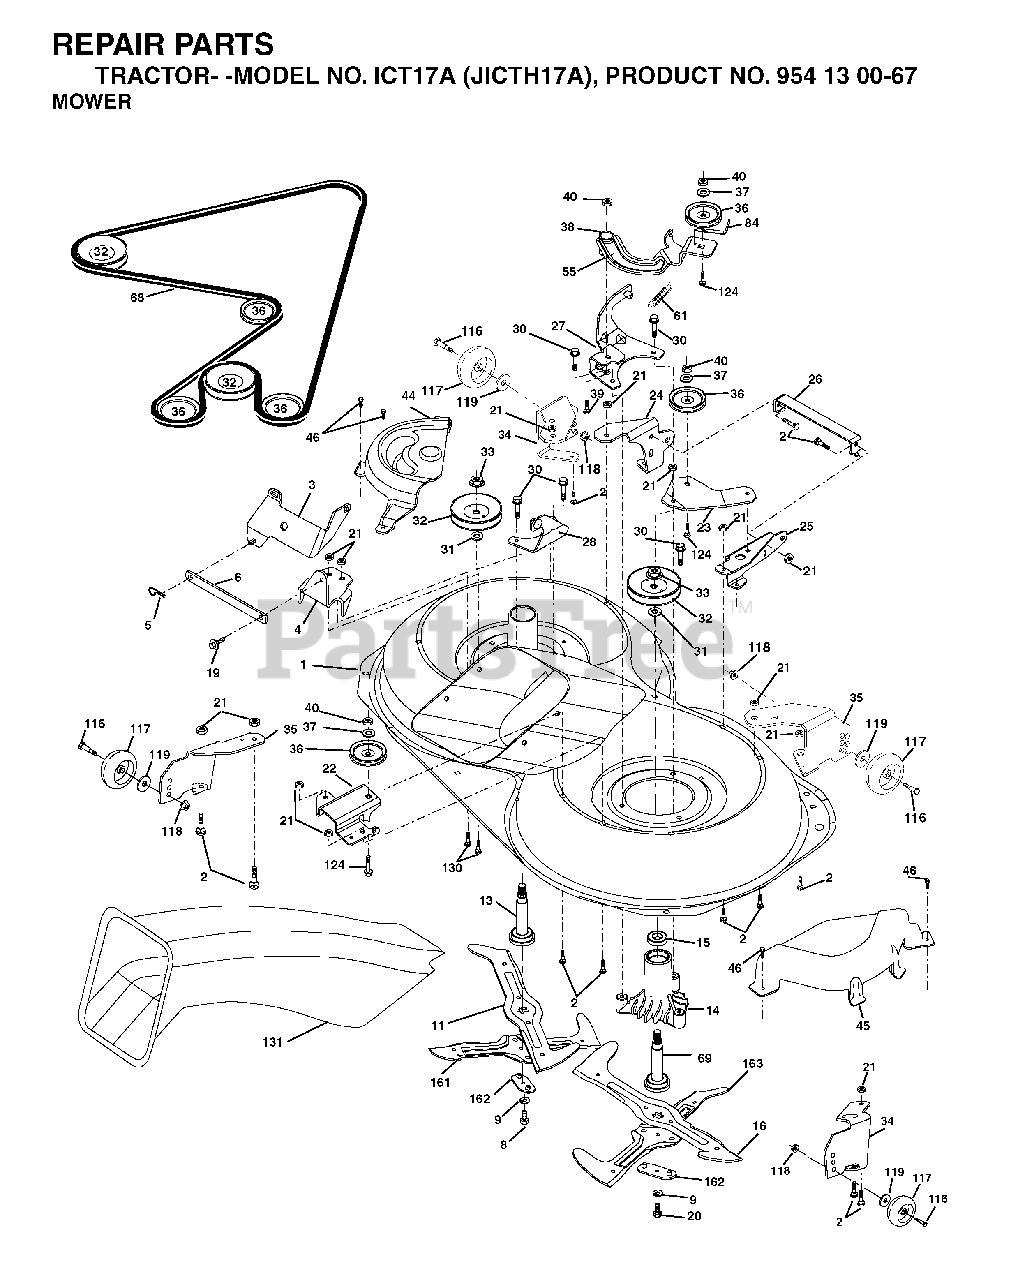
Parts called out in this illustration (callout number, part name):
2	BOLT
3	BRACKET
5	RETAINER-SPRNG RB
6	BAR SWAY
9	LOCKWASHER
11	BLADE.3N1.LH.CRD
13	SHAFT ASM VENT
14	HSG MANDREL
16	BLADE.3N1.RH.CRD
19	BOLT SHD 5/16-18
21	LOCKNUT
22	BRACKET
23	BRACKET
26	BRACE
27	BRACKET
30	SCREW, WASHER HEAD
31	WASHER
33	NUT, FLG TOPLOCK 9/16"
36	PULLEY.IDLER.4.25
40	LOCKNUT
45	MANDREL COVER
46	SCREW.1/4-20X5/8
55	ARM IDLER
68	HEX-BELT 107 MOWER
69	SHAFT.ASM.W/LWR.BRG.RH.THREAD
84	KEEPER, BELT IDLER
116	BOLT, SHOULDER
117	WHEEL GAGE DONUT
118	LOCKNUT
119	WASHER
124	BOLT.3/8-16X1.50
131	CHUTE BAGGER
